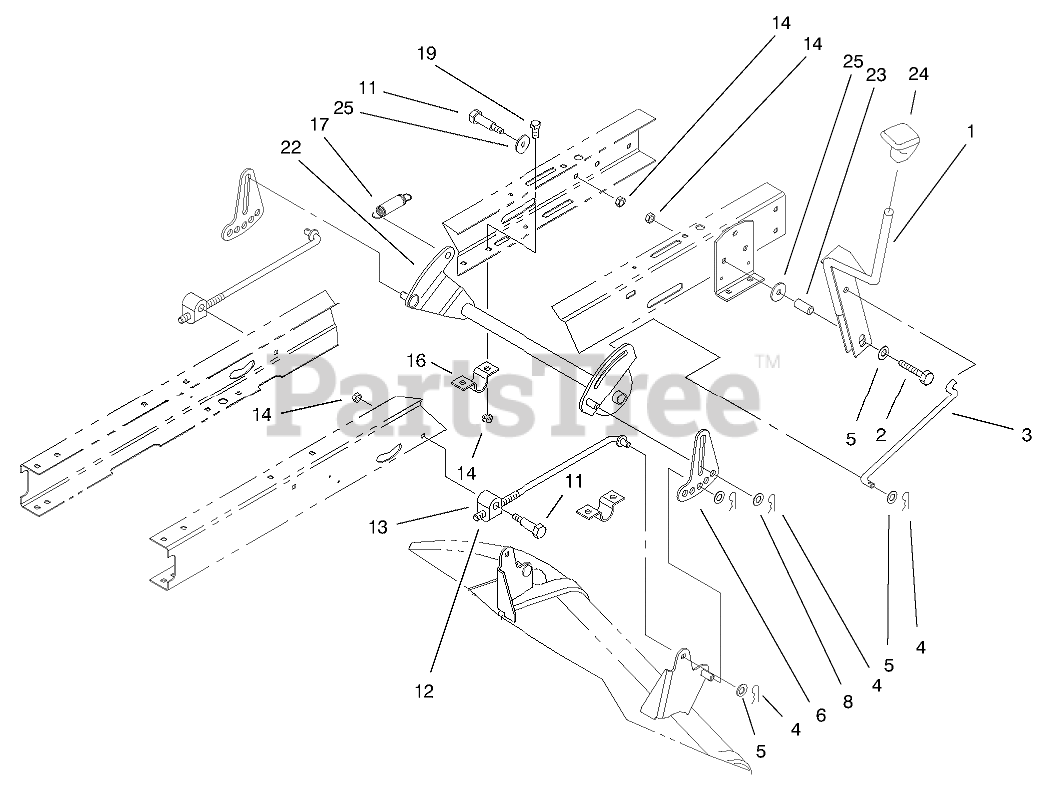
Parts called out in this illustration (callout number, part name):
1	HOC LEVER ASM
2	SCREW-HH
3	LINK-HOC
4	PIN-COTTER
5	WASHER-FLAT
6	LINK-ADJUSTING, HOC
8	WASHER-HARDENED
11	SCREW-SHOULDER, HH
12	ROD-HANGER, REAR
13	TRUNNION-HOC
14	NUT-LOCK, NI
16	CLAMP-PIVOT, HOC
17	SPRING-EXTENSION
19	SCREW-HH
22	PIVOT ASM
23	SPACER
24	KNOB-SHIFT
25	WASHER-PIVOT
